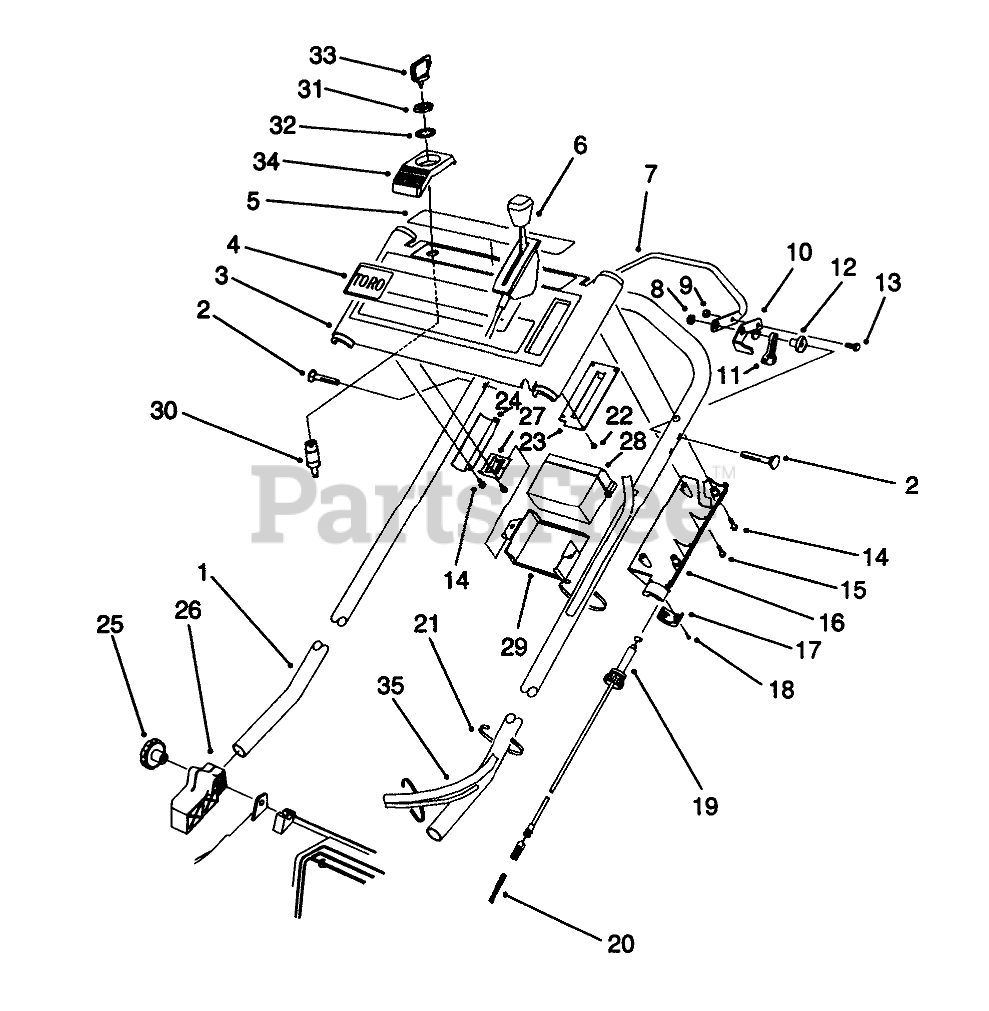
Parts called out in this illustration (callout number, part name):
1	Handle
2	SCREW-HANDLE
3	Panel-Control (Incl Ref. #4, & 5)
4	DECAL - TORO
5	DECAL - DANGER PANEL
6	THROTTLE CONTROL
7	CONTROL BAR
8	NUT-LOCK, NI
9	NUT-LOCK, NI
10	CONTROL LEVER
11	LEVER-TRACTION
12	SPACER-SUPPORT
13	SCREW-HH
14	SCREW-PPH, PLASTITE
15	Screw
16	Cover-Throttle Lower
17	LOWER THROTTLE CAP
18	#4-14X.62 PLASTITE SCW
19	TRACTION CABLE
20	SPRING-COMPRESSION
21	TIE-CABLE
22	#6-19X.25 PLASK FORM SC
23	THROTTLE PLATE
24	Bracket-Panel
26	MOUNT-HANDLE, RH
27	BATTERY BRACKET
28	Battery
29	BATTERY RETAINER
30	Switch-Starter (Incl. Ref. #31, & 32)
31	NUT-HH
32	WASHER-TOOTH, INTERNAL
33	KEY-IGNITION
34	IGNITION SWITCH BRACKET
35	Harness-Wire
